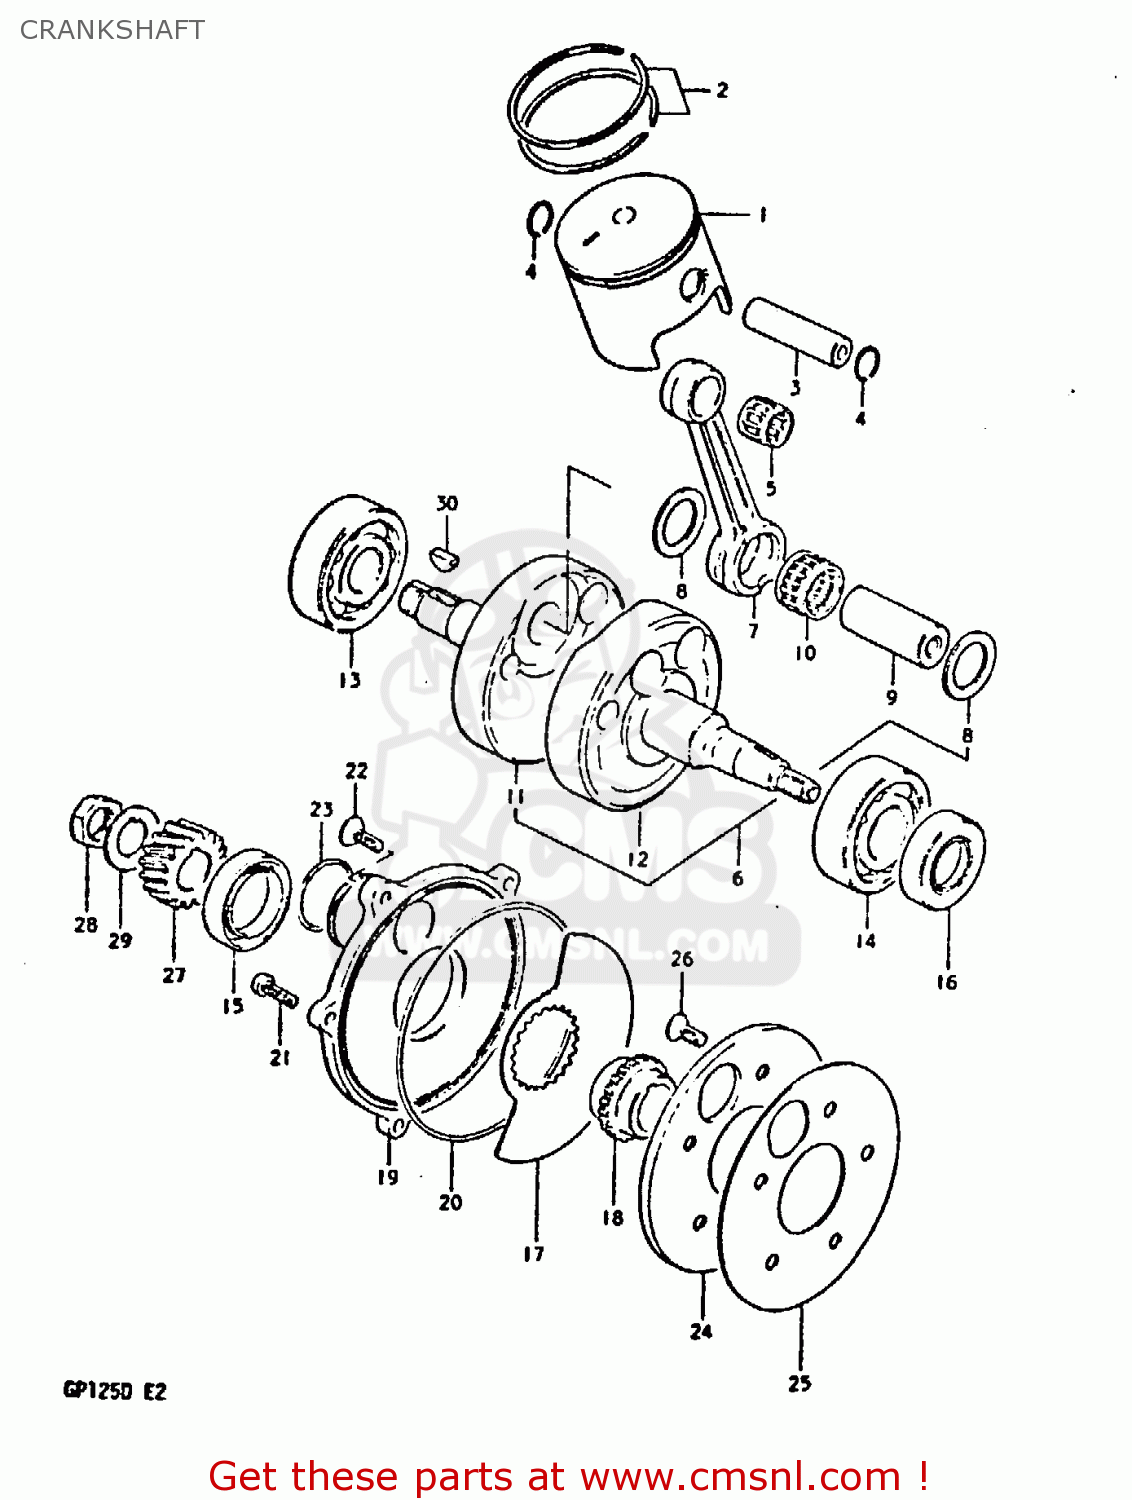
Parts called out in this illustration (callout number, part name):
1	PISTON
2	RING SET,PISTON
3	PIN,PISTON
4	RING,SNAP 14MM
5	BEARING
6	CRANKSHAFT ASSY
7	CONNECTING ROD
8	WASHER(19X32X1)
9	PIN,CRANK
10	BEARING(19X25X16)
11	CRANKSHAFT,R
12	CRANKSHAFT, LH
13	BEARING
14	BEARING
15	SEAL,OIL(30X44X7)
16	SEAL,OIL(25X44X7)
17	PLATE,CRANKSHAFT VALVE
18	GUIDE, VALVE
19	SEAT, OUTER VALVE
20	O RING(D:2,ID:108.6)
21	SCREW
22	SCREW
23	O RING(D:2.4,ID:28.7)
24	SEAT,CRANKCASE INNER VALVE
25	GASKET
26	SCREW
27	GEAR,PRIMARY DRIVE
28	NUT
29	WASHER
30	KEY
